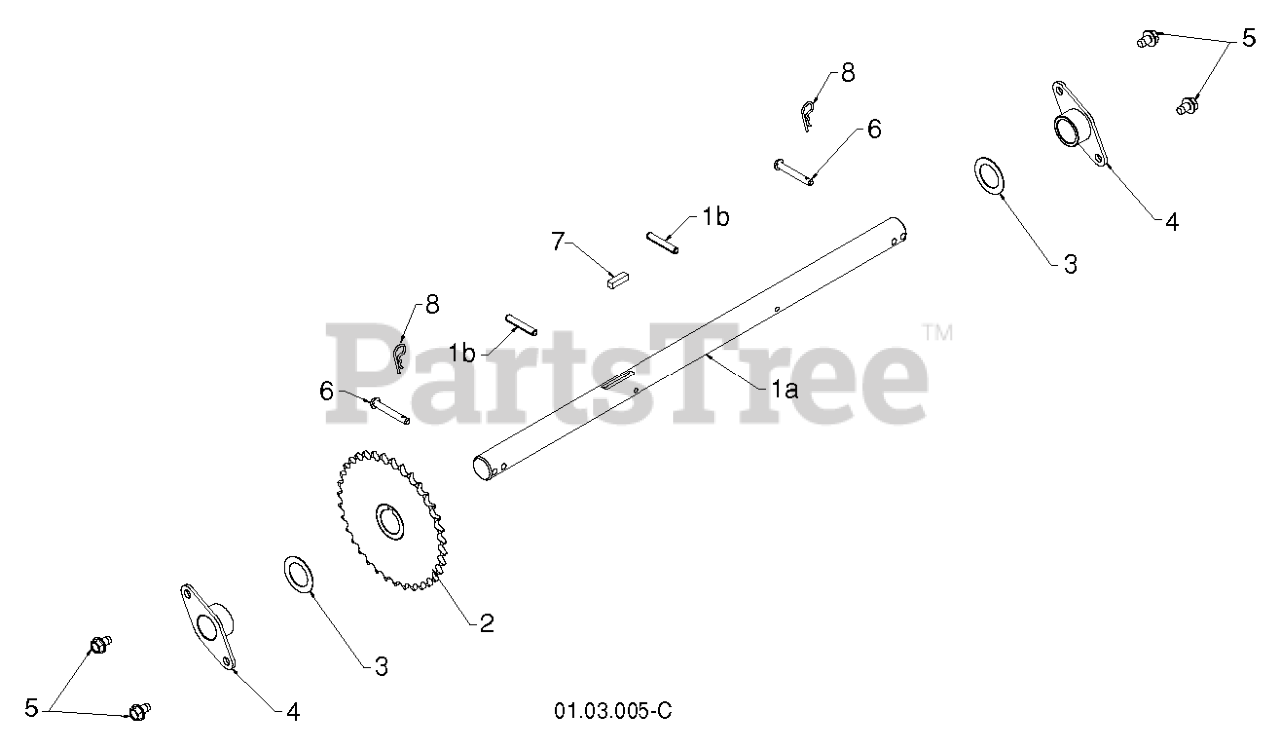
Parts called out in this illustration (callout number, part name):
1	AXLE.SHAFT.ASM.W/ROLPIN.NON-PS
2	SPROCKET.WELDMENT.AXLE.1.00
3	WASHER TRUST 1"
4	BEARING, AXLE
5	Screw 5/16-18 x 1/2 Hex, Self Tapping 5/16-18 x 1/2
6	RIVET
7	KEY, SQUARE 1/4 X .875
8	RETAINER M
